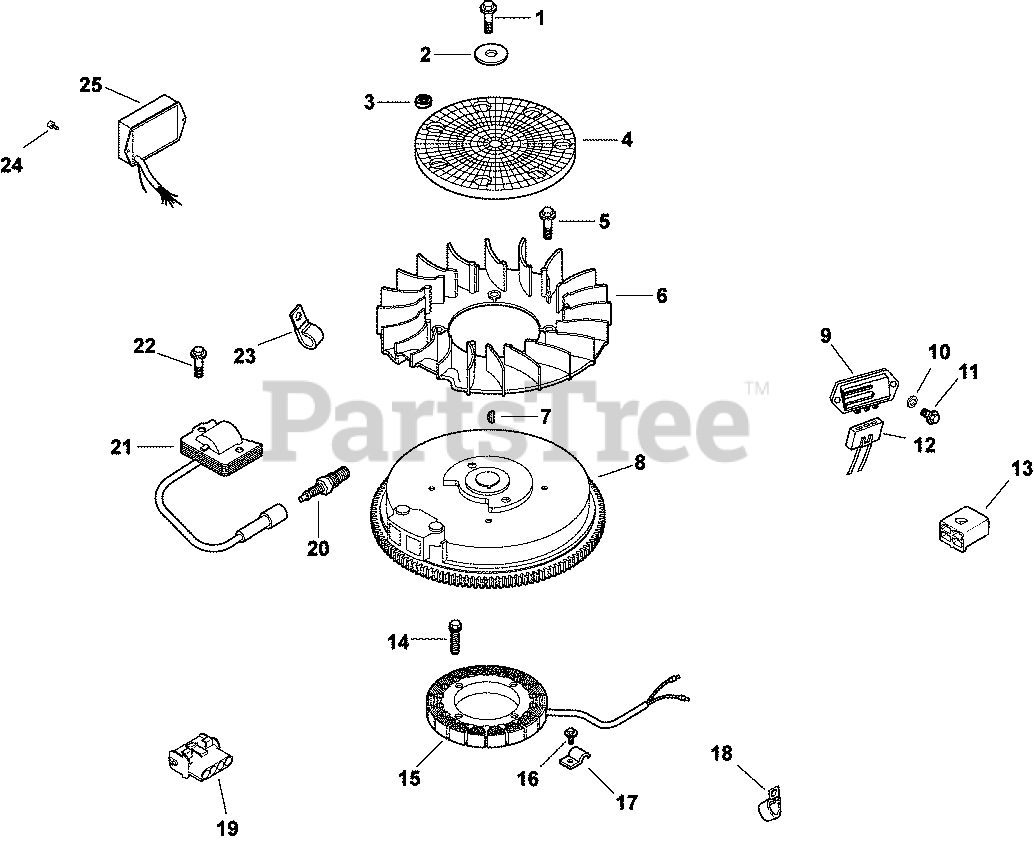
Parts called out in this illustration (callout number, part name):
1	SCREW, FLG M10X1.5X45 - (#25086361S)
2	WASHER, FLAT 13/32"
4	SCREEN, GRASS
5	BOLT, SHOULDER
7	KEY, 3/16" X 5/8"
8	FLYWHEEL - DISCONTINUED
9	REG/RECT-15 AMP (KM)-USE 41 403 10-S
10	WASHER, FLAT 3/16"
11	SCREW, WSH HD TAP #8-18X1"-DISC.
12	CONNECTOR, BODY (KM)-USE 25 155 41-S
13	CONNECTOR
14	SCREW, M5X0.8X25 - (#25086402S)
15	STATOR - USE 12 085 09-S
16	SCREW, FLG THD FRM M5X.8X10
18	CLIP, REGULATOR/RECTIFIER
19	CONNECTOR
20	PLUG, SPARK (STD)
21	MODULE, IGNITION
22	SCREW, SCKT THRD FRMM5X0.8X20 - DISCONTINUED
23	CLIP, CABLE
24	SCREW, PHL THD FRM M4.2X13
25	MODULE, DIGITAL SPD ADV-USE 12 707 01-S
